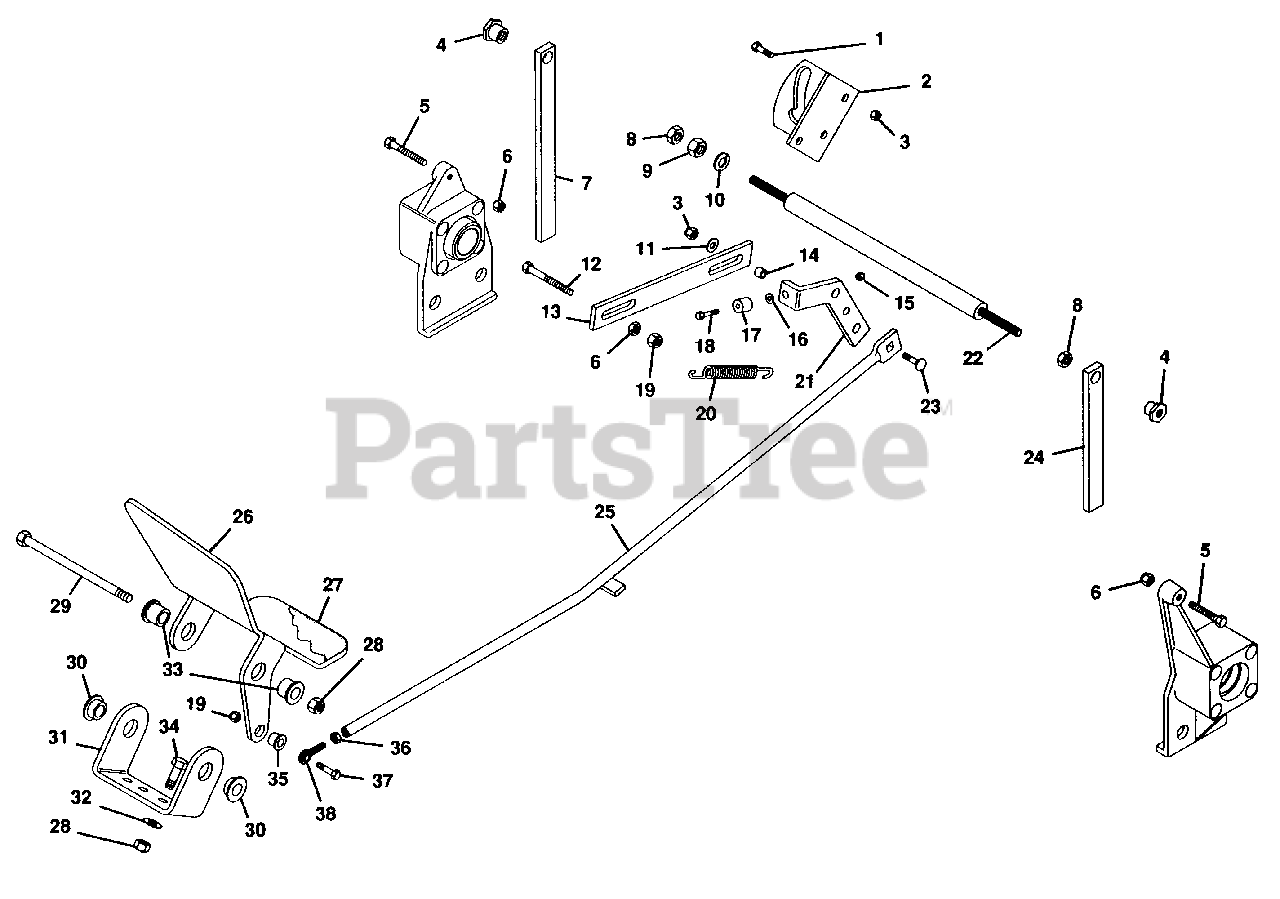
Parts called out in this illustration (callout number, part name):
1	BOLT, HEX 5/16-18X1.00
2	WELDMENT, FWD-REV ACTUATING
3	NUT, LOCK 5/16-18
4	BUSHING, FWD-REV SLIDE ROD
5	BOLT, HEX 3/8-16X2.50
6	NUT, HEX 3/8-16
7	SPRING, REVERSE CLUTCH
8	NUT, JAM 1/2-13 HEX
9	NUT, HEX 1/2-13
10	WASHER, LOCK 1/2 SP HEAVY
11	WASHER, FLAT .313X.875X.065
12	BOLT, HEX 3/8-16X3.00
13	STRAP, NEUTRAL DETENT
14	BUSHING, FWD-REV LINKAGE
15	NUT, LOCK 1/4-28
16	WASHER, FLAT .281X.625X.065
17	ROLLER, CLUTCH CAM
18	BOLT, HEX 1/4-28X1.38 GR. 8
19	NUT, LOCK 3/8-16
20	SPRING, NEUTRAL DETENT
21	ARM, FWD-REV CLUTCH ROLL
22	ROD, FWD-REV SLIDE
23	BOLT, 5/16-18X1.25 RD HD SQ NK
24	SPRING, FWD-REV CLUTCH
25	ROD, FWD-REV SHIFTER
26	PEDAL, FOOT CLUTCH
27	PAD, FOOT CLUTCH PEDAL
28	NUT, LOCK 1/2-13
29	BOLT, HEX 1/2-13X6.50
30	BUSHING, NYLON .76X1.00X.76 FLG
31	BRACKET, CLUTCH PEDAL PIVOT
32	WASHER, FLAT .531X1.250X.100
33	BUSHING, .513X.750X.625
34	BOLT, HEX 1/2-13X1.25
35	BUSHING, NYLON .32X.437X.248
36	NUT, JAM 3/8-24 HEX
37	BOLT, HEX 3/8-16X1.25
38	ROD END, MALE
